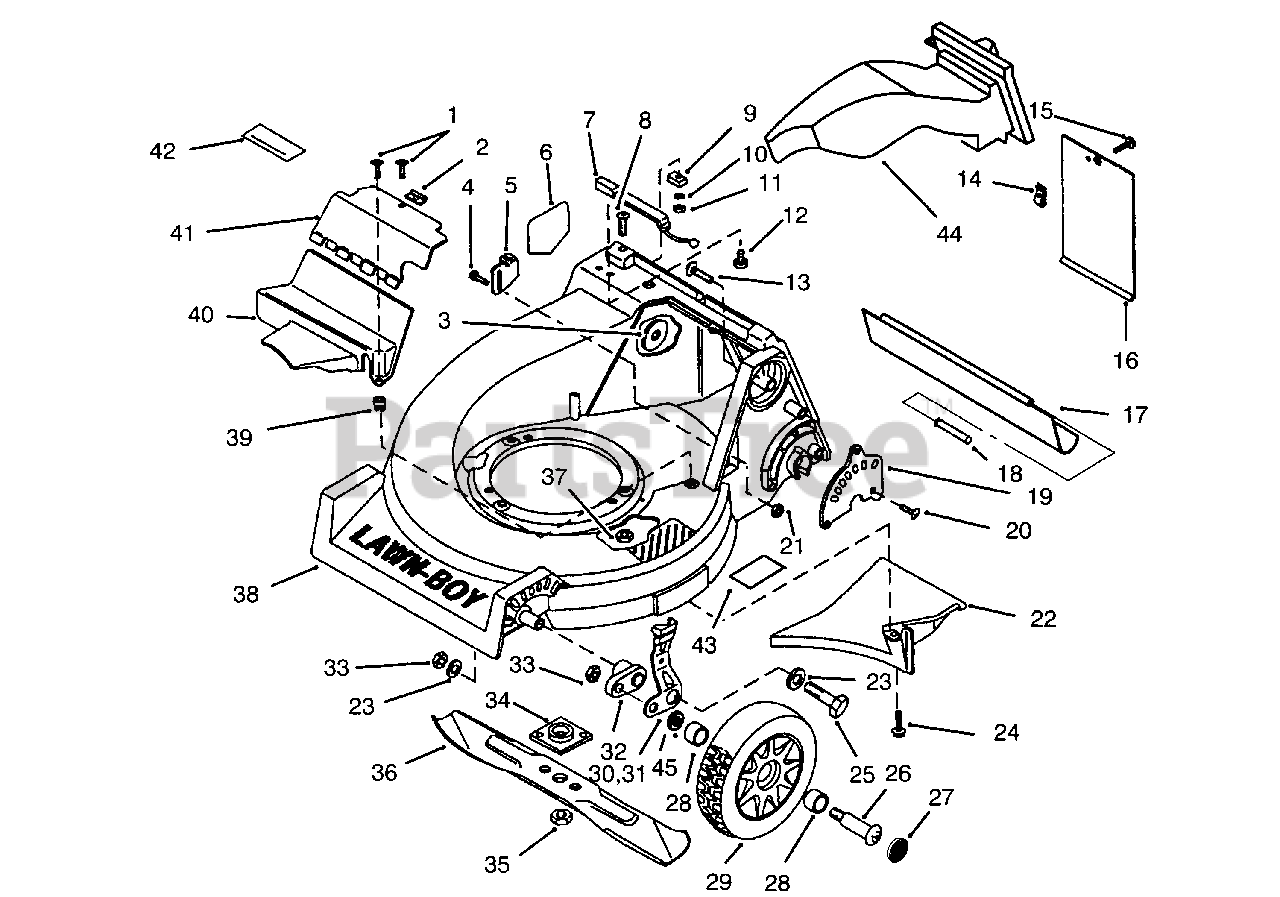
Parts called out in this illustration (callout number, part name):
2	Speednut
3	Washer-R.H. Handle
5	Anchor-Cable
6	Decal-Blade Warning
7	Switch-Bag Lock
9	Assembly-Magnet
10	Lockwasher
13	Bolt-Handle Mounting
14	Speednut
16	Door-Access
17	Shield-Trailing
19	Plate-Height Adjust
20	Screw-Plate to Housing
21	Nut-Cable Anchor/Hsg.
24	Screw-Baffle to Housing
26	Shoulder Bolt-Wheel
29	Assembly-Wheel & Tire (Inch. Ref. No. 28)
30	Assy.-Knob & Spring, L.H.
32	Arm-Front Height Adj.
33	Nut-Jam
34	Assembly-Collar & Plate
35	Nut-Blade
36	Blade-21"
37	Locknut-Mtg Plate/Hsg.
38	Assembly-Housing (Incl. Ref. No. 3, 6,13, 22, & 24)
39	Grommet
40	Cover-Lower Drive
41	Cover-Upper Drive (Incl. Ref. No. 42)
42	Decal-Warning
43	Decal-Danger
44	Plug-Mulch (Whole Goods)
